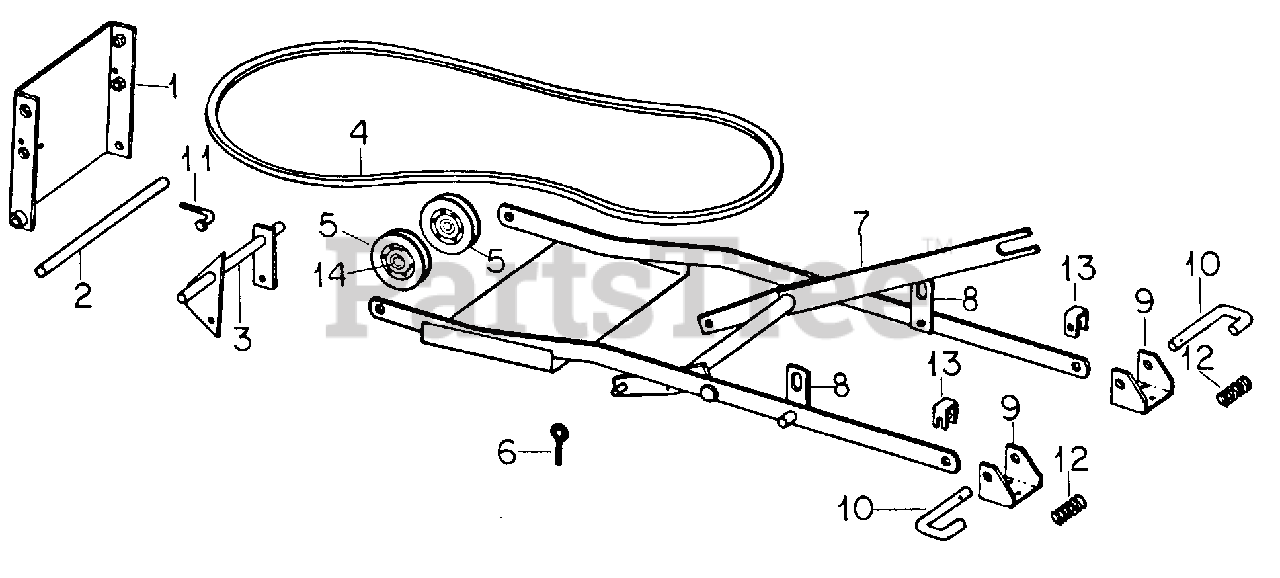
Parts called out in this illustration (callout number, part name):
1	Support Assy,Front
2	Pin, Front Mounting
3	Support Assy, Idler
5	Pulley, Drive Belt Idler
6	Eyebolt
7	Frame Assy, Lift
8	Link Assy, Lift
9	Bracket, Mower Support
10	Pin, Mower Support
12	Spring, Mower Support Pin
13	Bracket, Hitch Support
14	Bearing Assy, Idler Pulley
